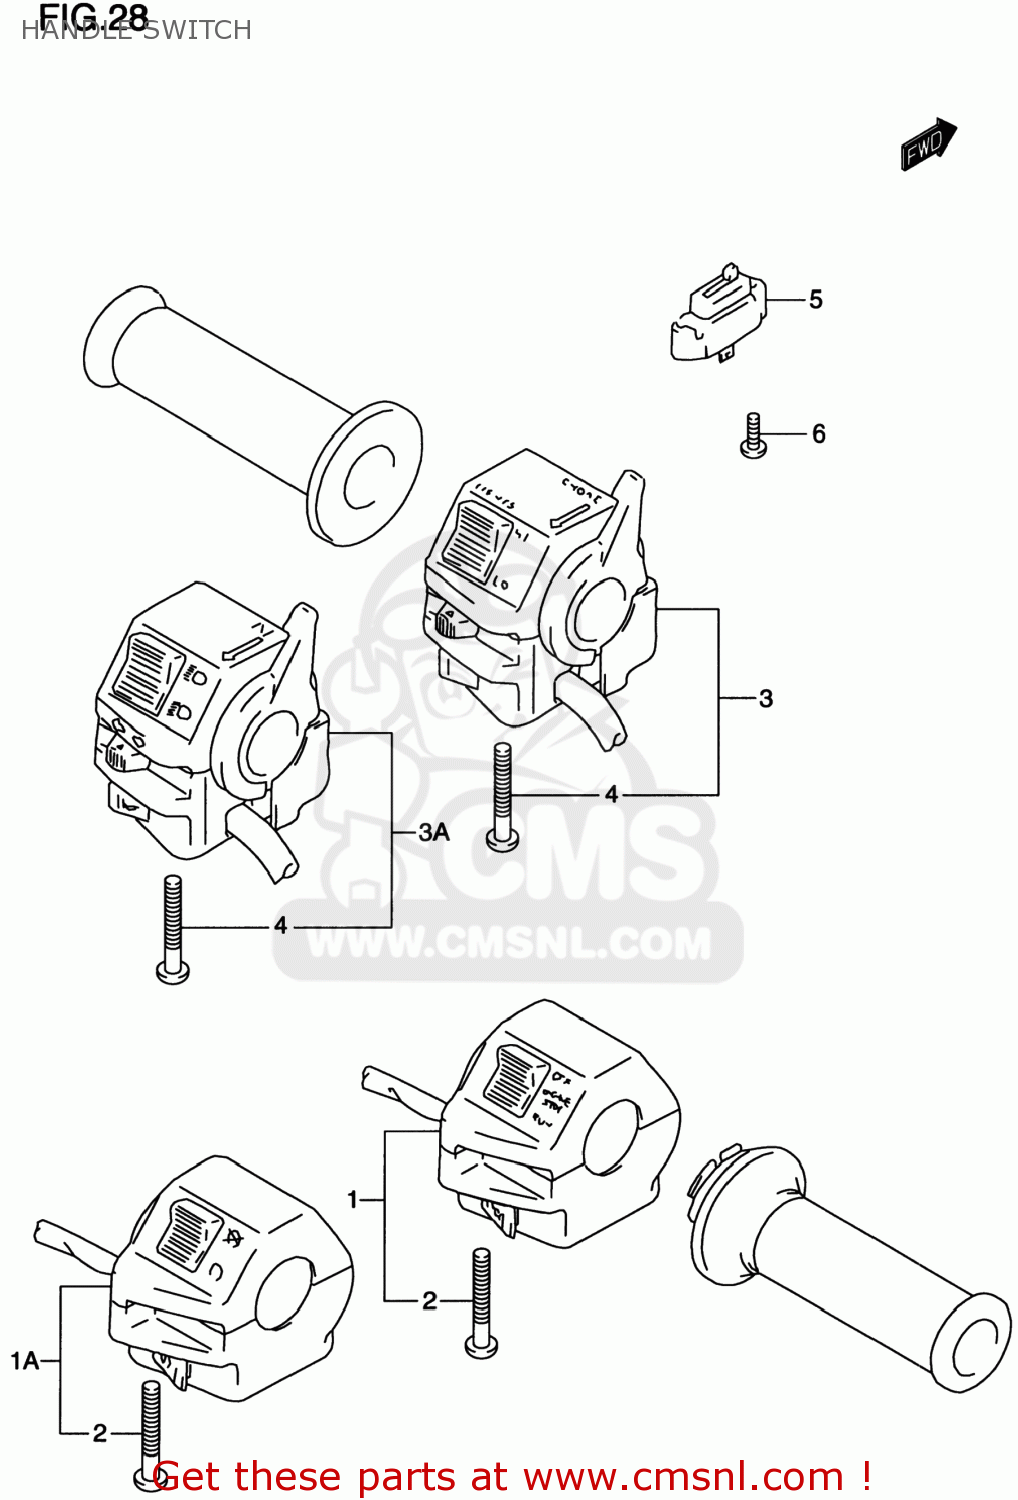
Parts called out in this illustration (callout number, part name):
1	SWITCH ASSEMBLY,RIGHT
1A	SWITCH ASSY,HANDLE,R
2	SCREW, 5X45
3	SWITCH ASSEMBLY,HANDLE,LEFT
3A	SWITCH ASSY,HANDLE,L
4	SCREW, 5X45
5	SWITCH ASSY,CLUTCH
6	SCREW
